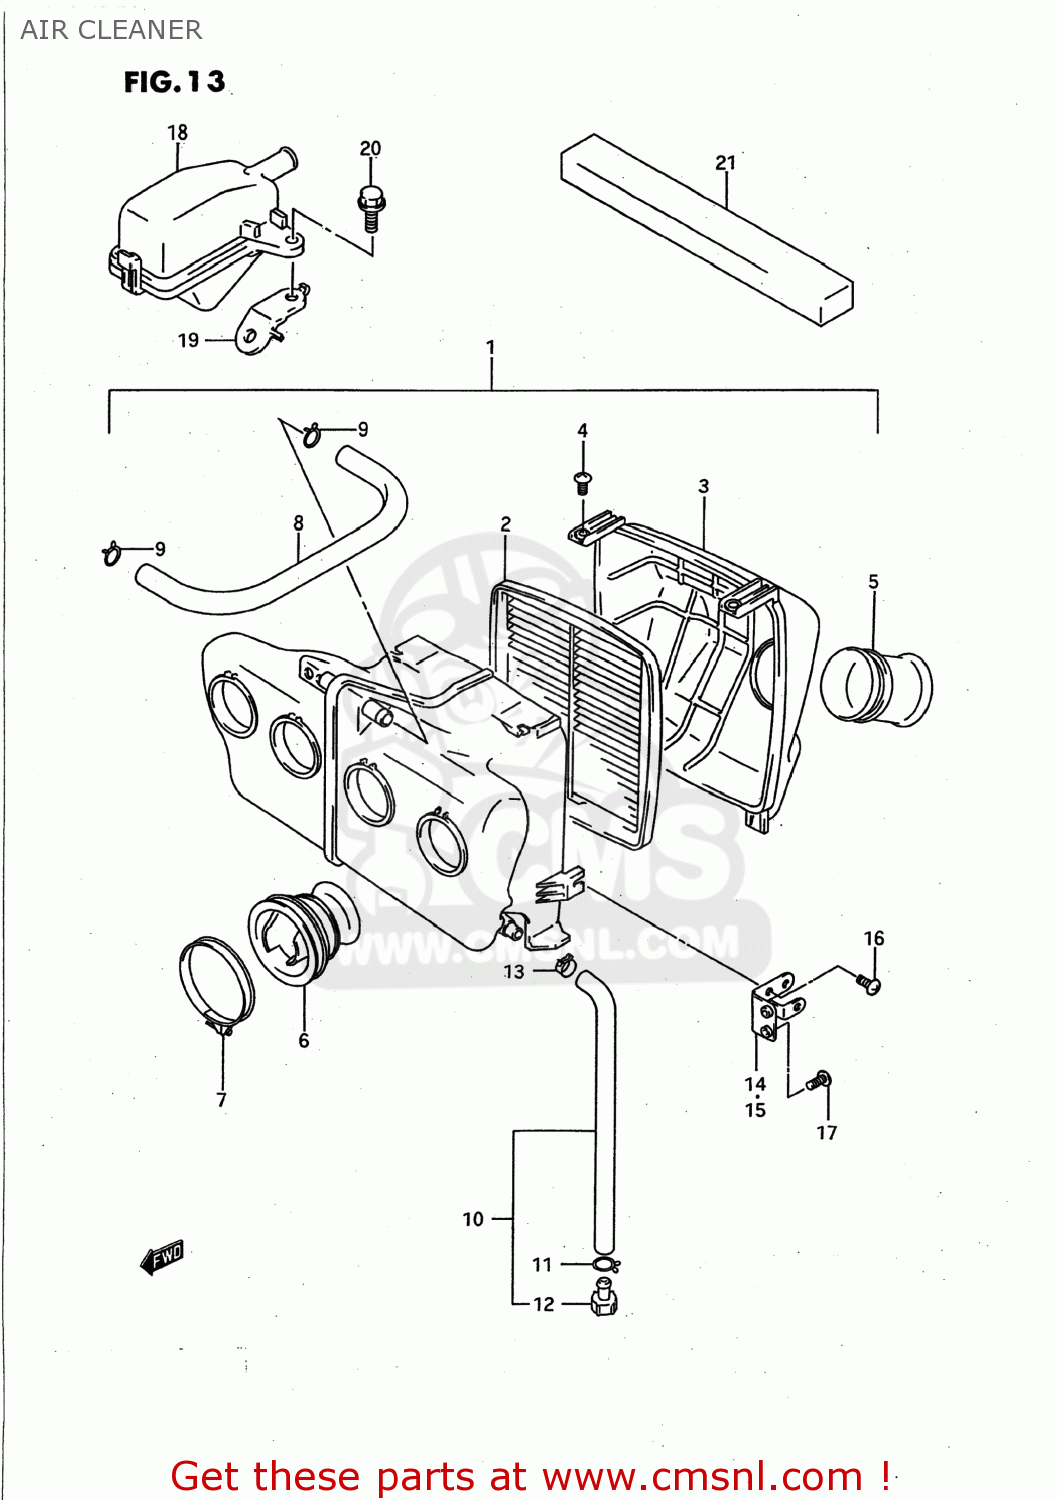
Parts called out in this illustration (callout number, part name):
1	CLEANER ASSEMBLY,AIR
2	FILTER,AIR
3	CAP,AIR CLEANER
4	SCREW, FRONT & REAR
5	TUBE,INLET
6	TUBE,OUTLET
7	CLAMP
8	TUBE,BREATHER
9	CLIP
10	TUBE,DRAIN
11	CLIP
12	STOPPER,DRAIN
13	CLIP
14	BRACKET COMP,AIR CLEANER
15	BRACKET COMP,AIR CLEANER
16	SCREW
17	SCREW
18	CLEANER ASSY,AIR NO.2
19	BRACKET,AIR CLEANER NO.2
20	BOLT
21	CUSHION,AIR SEAL
